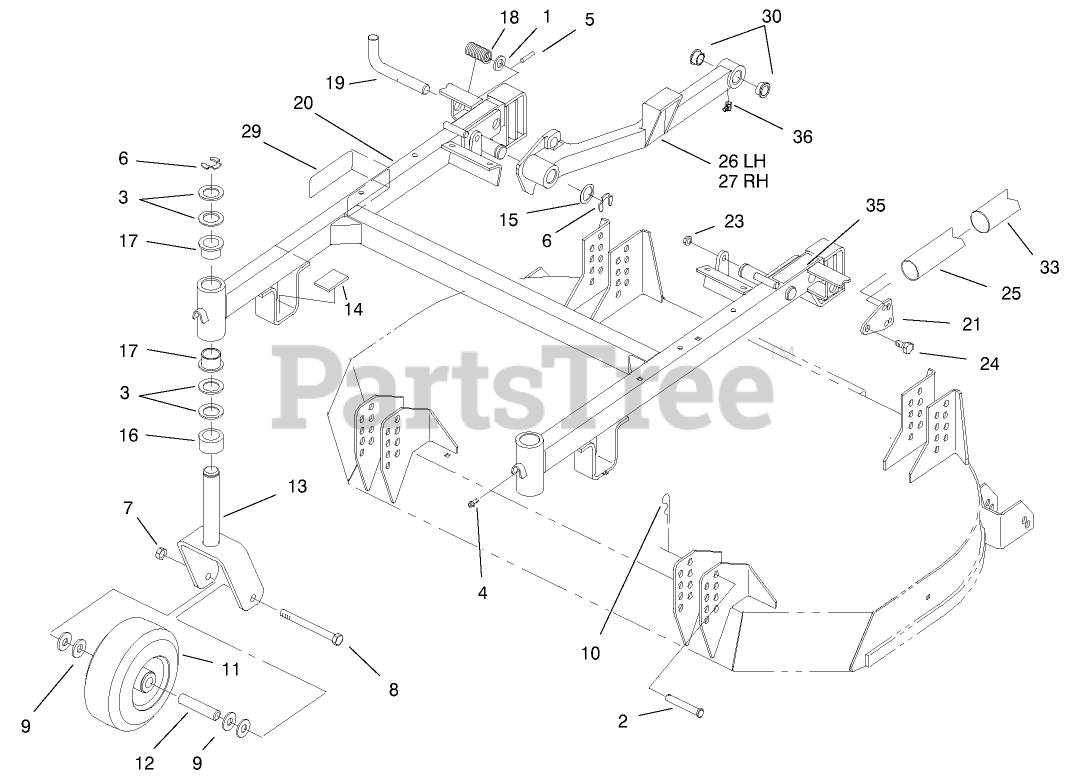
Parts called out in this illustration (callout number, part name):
1	Washer
2	PIN-CLEVIS
3	WASHER-THRUST
4	FITTING-GREASE
5	PIN-ROLL
6	RING-RETAINING
7	NUT-HEX
8	SCREW-HH
9	WASHER-FLAT
10	PIN-HAIR
11	CASTOR WHEEL ASM
12	SPANNER-TIRE
13	Castor Fork
14	CUSHION - RUBBER
15	Washer
16	SPACER-CASTOR
17	BUSHING
18	SPRING-COMPRESSION
19	PIN - PIVOT
20	Frame-Carrier
21	PLATE-END, SPRING
23	NUT-LOCK, NI
24	BOLT-SHOULDER
25	SPRING-EXTENSION
26	LH PUSH ARM / BUSHING
27	RH PUSH ARM / BUSHING
29	DECAL - HOC CE-OBS
30	BEARING-FLANGE
33	COVER-SPRING
35	DECAL-WARNING
36	FITTING-GREASE
